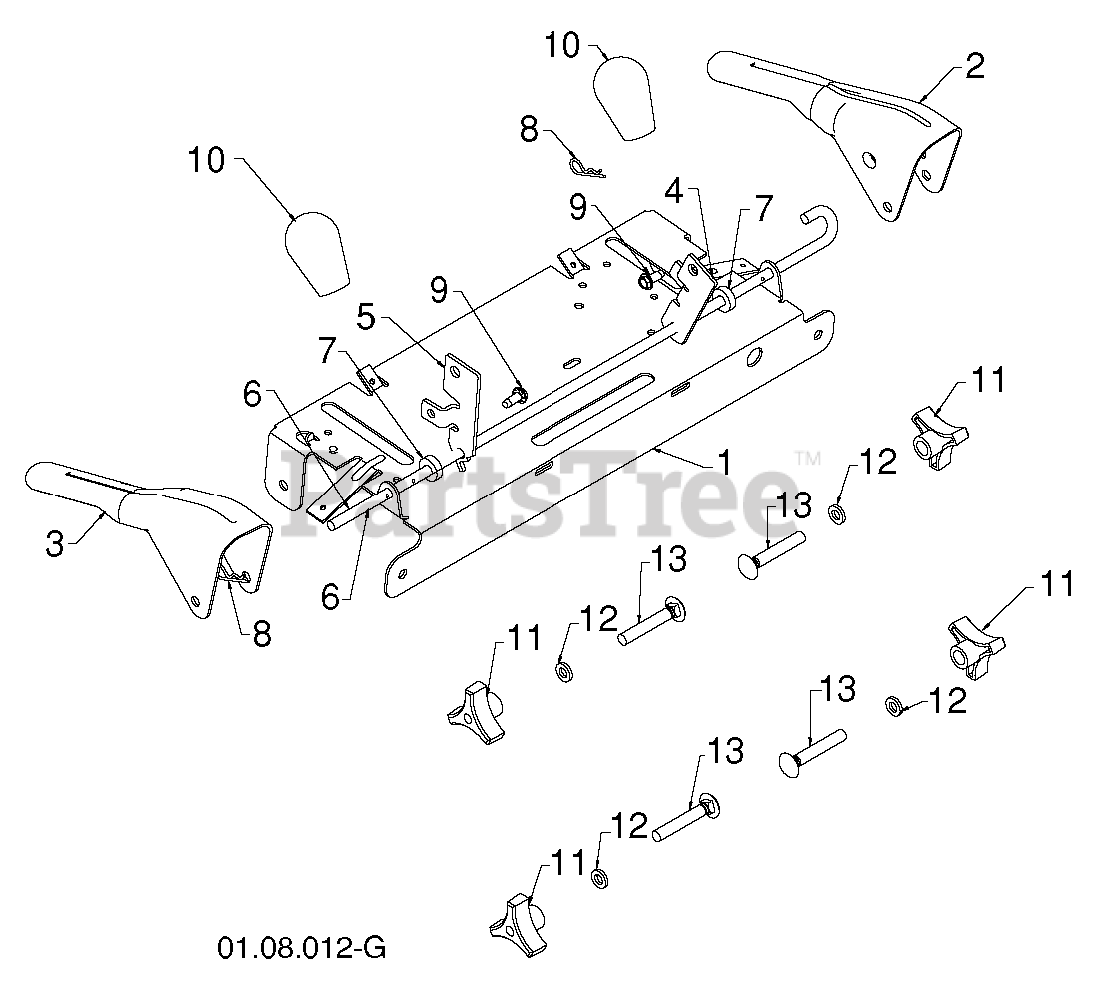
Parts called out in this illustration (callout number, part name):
1	PANEL.CONTROL.PNT.BLACK
2	LEVER.CONTROL.LH.BLACK
3	LEVER.CONTROL.RH.GREY
4	ARM.TRACTION.ROD.YZ
5	ARM.IMPELLER.ROD.SNOW
6	BAIL.CONTROL.INTERLOCK
7	SPACER.CONTROL.LEVER
8	RETAINER
9	SCREW 14-20 X 5/8
10	KNOB LEVER, BLACK
11	KNOB.HANDLE.3/8.TRI-POINT.BLAC
12	WASHER
13	BOLT 3/8-16 X 2-1/4
